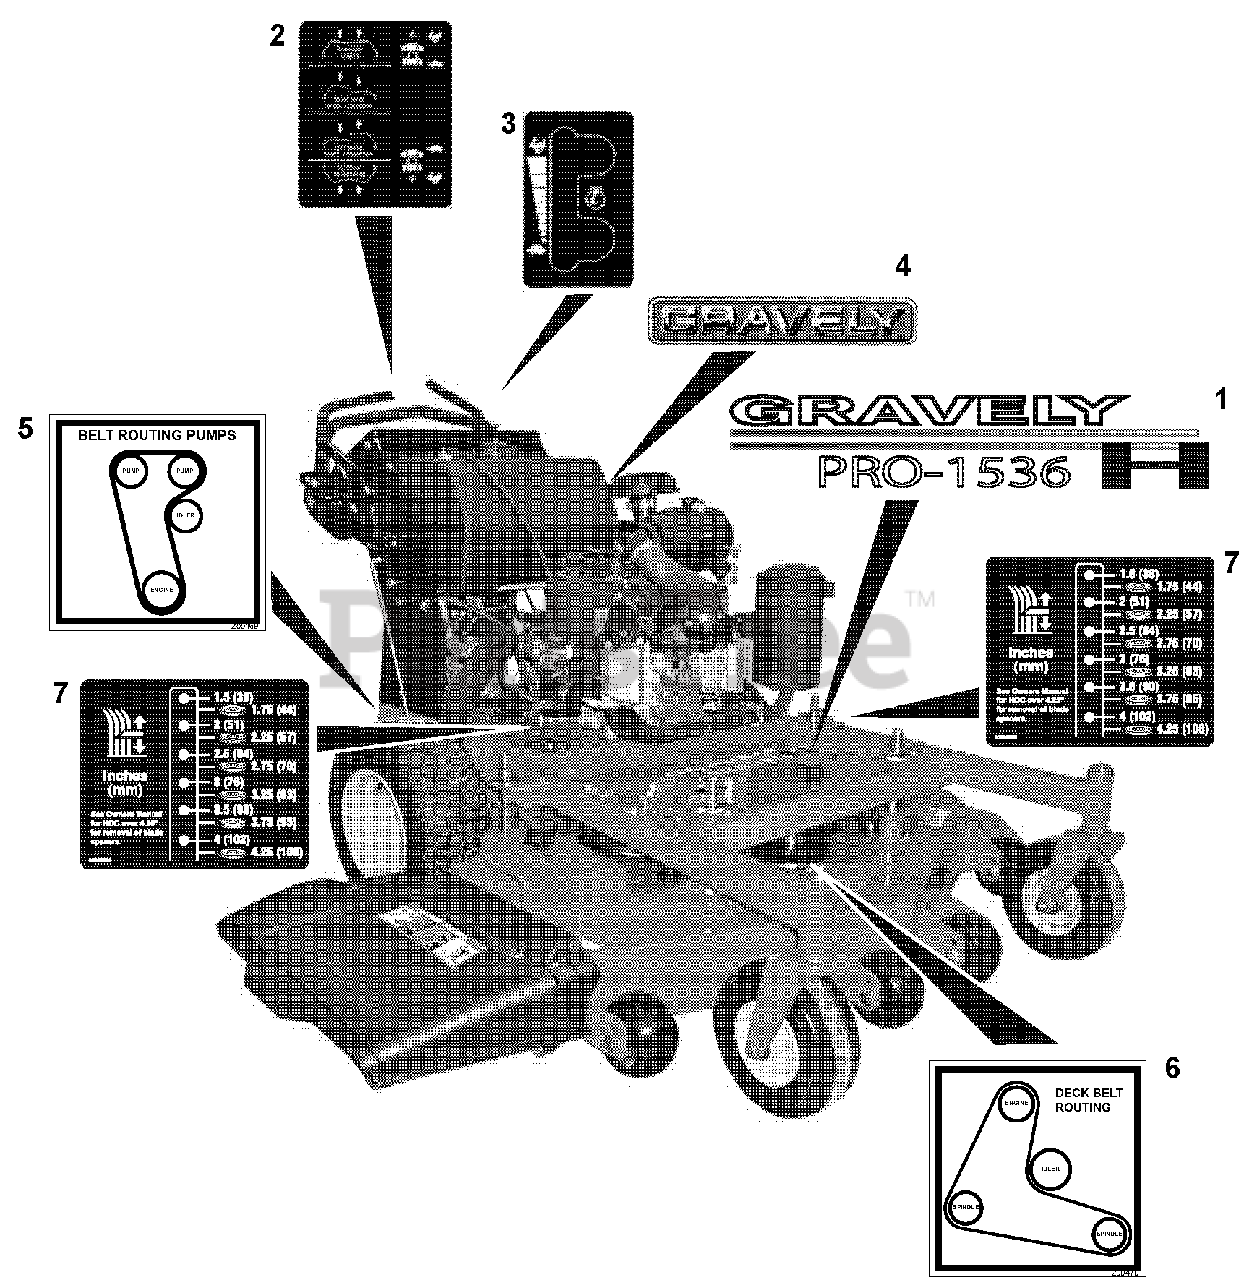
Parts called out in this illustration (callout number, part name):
1	Decal, Gravely Pro 1536H (988146)
2	Decal, Directional Control
3	Decal, Throttle
4	Decal, Gravely B 6.5"
5	Decal, Pump Belt Routing
6	Decal, 36" Deck Belt Routing (988146)
7	Decal, Pro Walk Height of Cut
